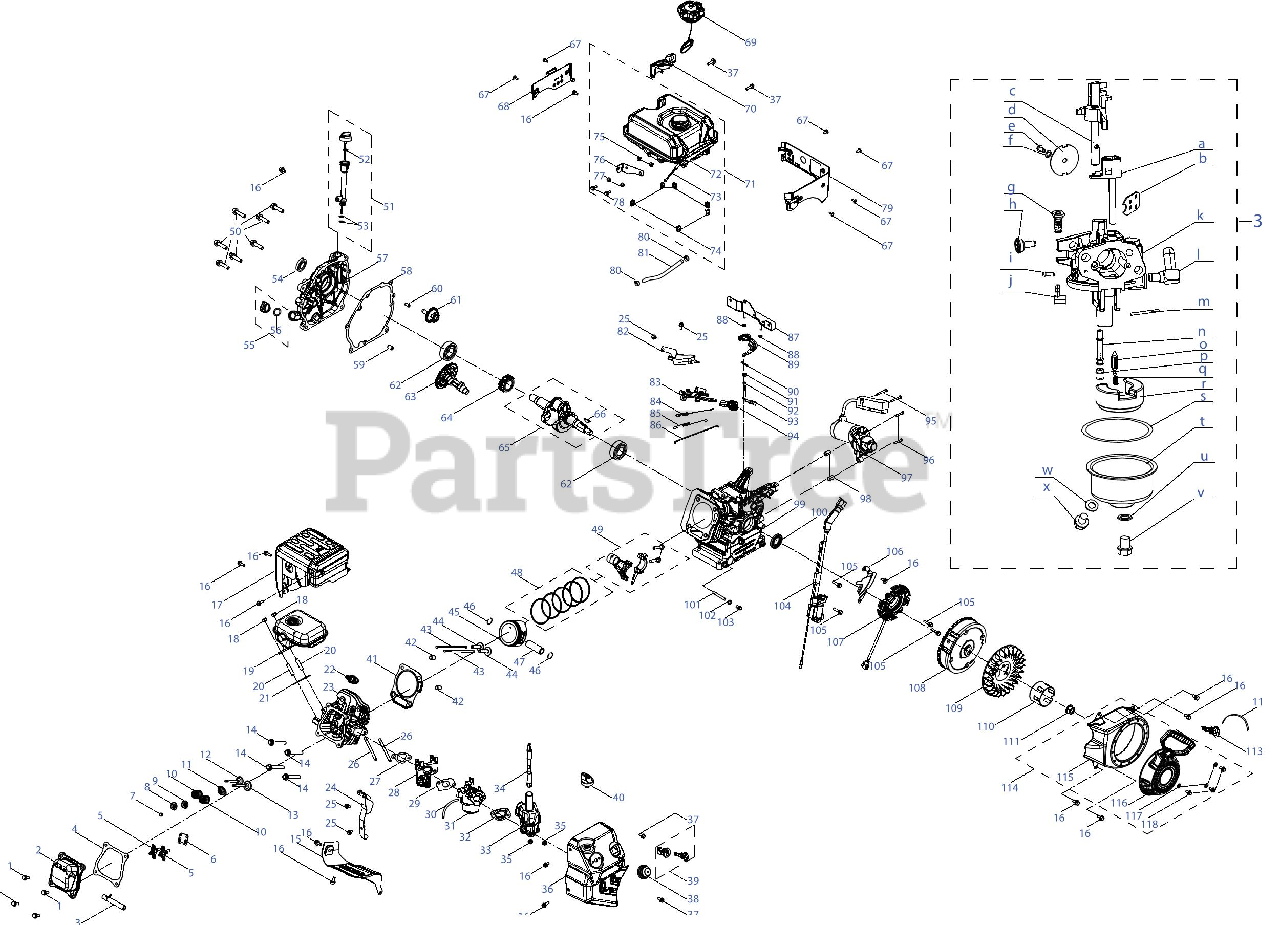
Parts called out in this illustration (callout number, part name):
1	Bolt, M6x16
2	Valve Cover
3	Breather Hose
4	Gasket, Valve Cover
5	Rocker Arm Assembly
6	Rocker Arm Base
7	Valve Adjust Cap, Exhaust
8	Valve Spring Seat
9	Valve Spring Seat
10	Valve Spring
11	Intake Valve Seal
12	Exhaust Valve
13	Intake Vavle
14	Bolt, M8x55
16	Bolt, M6x12
17	Muffler Guard
20	Stud, M8x34
21	Gasket, Muffler
22	Spark Plug
23	Cylinder Head
24	Snow Guard
25	Bolt, M6x12
26	Stud, M6x90
27	Gasket, Carburetor Insulator
29	Gasket, Carburetor
30	Fuel Hose,3.2x6.5x170
31	Carburetor
32	Gasket, Air Filter
33	Heater Box
34	Choke Linkage
36	Control Panel
37	Bolt, M6x18
39	Stop Switch
40	Choke Lever
41	Gasket, Cylinder Head
42	Pin, 10x16
43	Push Rod
47	Piston Pin
48	Piston Ring Set
49	Connecting Rod Assembly
50	Bolt, M8x32
51	Dipstick
52	O-Ring, 21x2.77
53	O-Ring, 15.2x1.5
54	Oil Seal, 25x41.25x6
56	O-Ring, 15.8x2.5
57	Crankcase Cover
58	Gasket, Crankcase
59	Pin, 9x14
60	Pin, 7x14
61	Governor Gear
62	Bearing, 6205
64	Drive Timing Gear
65	Crankshaft
66	Woodruff Key
67	Bolt, M5x14
68	Decorative Sheet, Right
70	Decorative Cover
71	Fuel Tank Assembly
72	Fuel Tank
73	Fuel Filter
74	Fuel Tank Mount Thread Tab
76	Fuel Tank Mount Tab
77	Washer, 6.5x1.5x12
78	Bolt, M6x20
79	Decorative Sheet, Left
80	Clamp
81	Fuel Hose, 6.3x12.5x162
82	Governor Shield
83	Governor Gear Bracket Assembly
84	Governor Spring
85	Idle Spring
86	Throttle Linkage
87	Fuel Tank Bracket
89	Governor Lever
90	Cotter Pin
91	Oil Seal, 6x11x4
92	O-Ring, 5.2x1.9
93	Governor Gear Shaft
94	Throttle Lever Knob
95	Screw, M4x48
96	Bolt, M6x32
97	Electric Starter
98	Pin, 8x8
100	Oil Seal, 25x41.25x6
101	Oil Drain Pipe
102	Washer, 10x1.5x16
103	Earth Bolt
104	Ignition Module
105	Bolt, M6x25
106	Lower Shield
107	Charging Coil
109	Cooling Fan
110	Starter Cup
111	Nut, M14x1.5
112	Tape, L=150mm
113	Stop Switch Key
114	Recoil Starter
115	Blower Housing
116	Recoil Starter
117	Washer, 6
118	Bolt, M6x10
